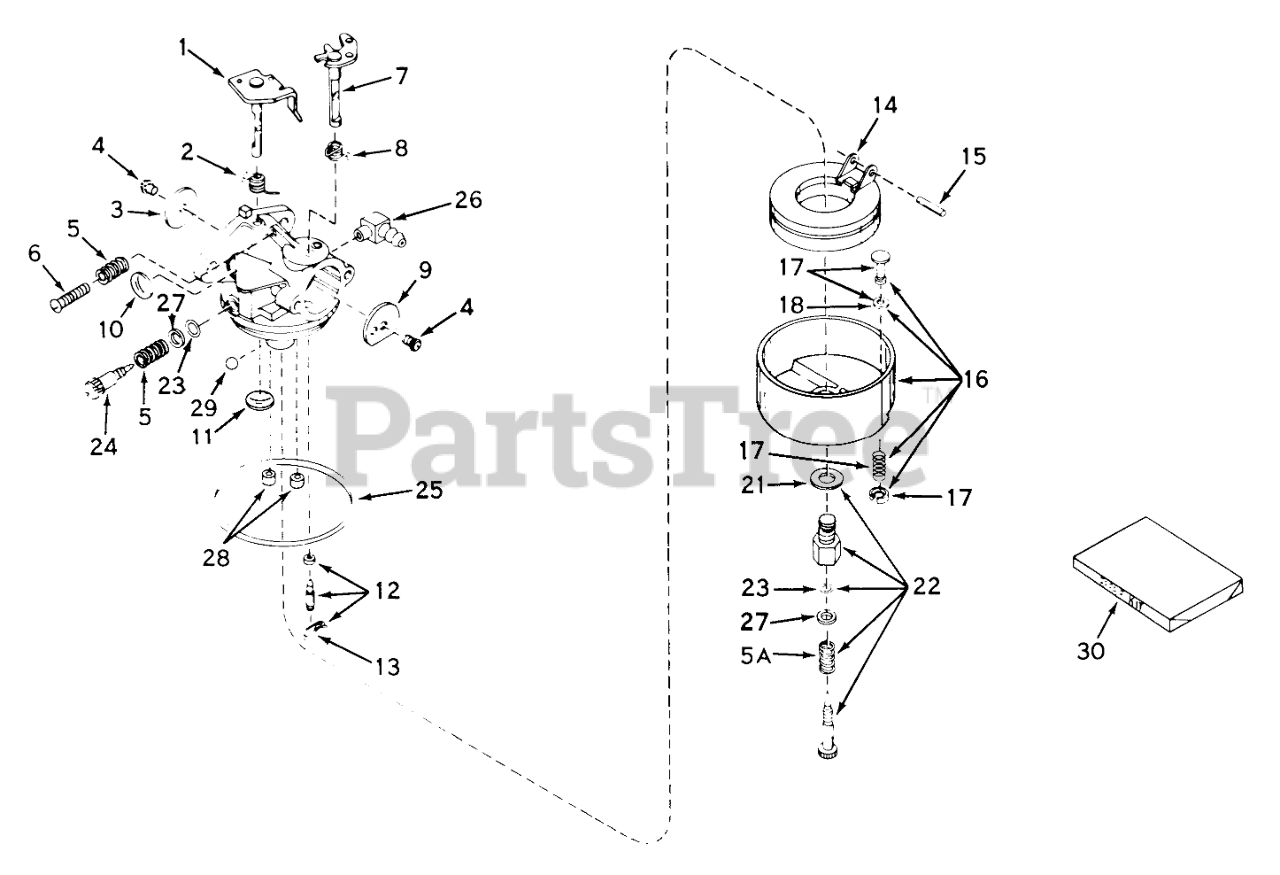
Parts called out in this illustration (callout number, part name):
1	Shaft & Lever Assy.
2	Spring Return
3	Shutter-Throttle
4	Screw-Shutter
5	Spring-Tension
6	Screw-Throttle Crack Screw / Idle Speed
7	Shaft& Lever Assy., Choke
8	Spring, Choke return
9	Shutter-Choke
10	Plug-Welch, Idle Mixture Well
11	Plug-Welch, Atmospheric Vent
12	Inlet Needle, Seat & Clip Assy (Incl. Ref. 13)
13	Clip-Spring
14	Float,Carburetor
15	Shaft-Float
16	Bowl & Drain Assy., Float (Incl. Ref. 17)
17	Plunger Assy., Drain (Incl. Ref. 18)
18	Gasket-Plunger, Drain
21	Washer-Bowl Nut
22	Adjustment Screw Assy., Main (Incl. Ref. 5A, 21, 23 & 27)
23	"O"Ring
24	Screw, Idle Adj.
25	O Ring-Bowl, Float
26	Fitting Fuel Inlet
28	Plug, Cup
29	BalI, Steel
30	Repair Kit
